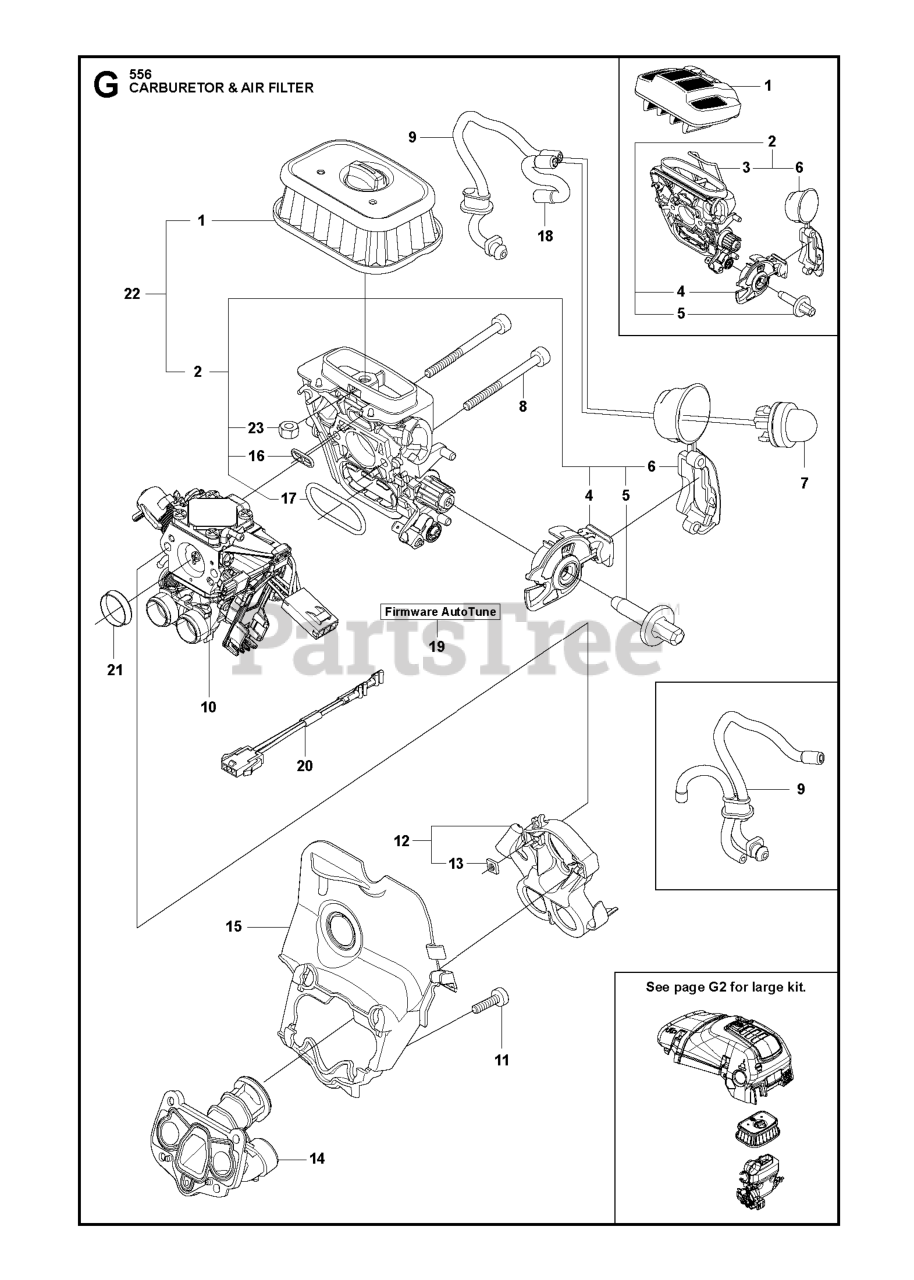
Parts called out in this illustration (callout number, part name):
3	APPLIQUE.SUBASM.GT.HUSQ.II
14	HOOD.ASM.HUSQVARNA.GT.TEX.ORAN
15	LENS.HEADLIGHT.LH.GTII.2011
18	GRILLE.SUBSTRATE.2011.
25	LENS.HEADLIGHT.RH.GTII.2011
34	PLATE.ENGINE.10GA.CRD.GENII
36	SCREW 5/16"
37	FENDER.TEX.SRD.CRD.BASE
52	LOCKNUT
62	BOLT D
68	Screw 5/16-18 x 1/2 Hex, Self Tapping 5/16-18 x 1/2
118	WASHER
130	SCREW.#10 X 0.750.BOS
137	BUMPER DASH
150	AIR DUCT.GTV2(1.66"RING HEIGHT
151	BRACKET.PIVOT.HOOD.GT.HUSQ.II
152	SHIELD.BROWNING.PNT.GT.V2
159	SCREW, 3/8-16X3/4
162	SCREW.HI-LO.CONSOLE
175	PLATE.CROSSMEMBER.HUSQ
176	SCREW.#10-24X5/8.RN.QU
177	BUSHING STEERING
178	CARGO.ASM.NET.TXGT.W/C
180	WELDMENT.CHASSIS.TEX.CRD.GEN.2
182	DASH DASH LOWER
183	BOLT.5/16-18X1-1/4 FULL THD
189	SCREW
191	INSERT.REFLECTIVE.RH.HUSQ.GTII
194	NUT LOCK HEX FLANGE 5/16-18
195	PLUG.HOLE.DASH.LOWER.12V.BLK
198	INDICATOR.DECK.LIFT.RED
199	PLATE DECK LIFT
202	VENT.SIDE.RH.GT.HUSQ.II.
203	VENT.SIDE.LH.GT.HUSQ.II.498
204	VENT.TOP.EXTERNAL.FILL.GT2.GRE
205	SIDE.TRIM.RH.GT.HUSQ.II
206	SIDE.TRIM.LH.GT.HUSQ.II.GRAY
207	BEZEL LIGHT.RH.GT.II.MYLAR
208	BEZEL LIGHT.LH.GT.II.MYLAR
213	BOLT
214	CLIP.RETAINER.TINNER.
217	ROD.PIVOT.HOOD
218	X-PIECE.HOOD.STOP.NON/
228	STUD.FASTNER.W/ANTI-ROTATE
229	LID.EXT.FILL.GT.HUSQ2.BLACK
234	BUMPER.HOOD.TEX.HUSQVARNA
235	SPACER FENDER
236	NUT.CENTERLOCK.5/16-
282	CLIP.RETAINER.CONSOLE.LT.HUSQ
283	CONSOLE.DECKLIFT.CRDII.498
287	SCREW 1/4X20
297	INSERT.REFLECTIVE.LH.HUSQ.GTII
308	BOLT.5/16-18UNCX3/4 W/SEMS.BLK
309	BACKPLATE.ASM.TEX.CRD.GEN2.1
319	LEVER.BAG.CRDII.ANTIROTATION
334	BRACKET.ENGINE
335	COVER.LOWER.DASH.RH.BLACK
336	COVER-LH.LOWER.DASH.GT2.BLACK
338	BOLT BOLT SHOULDER
339	LEVER LEVER BAGGER
340	BATTERY.DOOR.TEX.CRD.GEN.2,1
342	SUPPORT SUPPORT FENDER
343	CLIP CLIP
344	CONTROL.EZ.MULCH.TEX/CRD
345	RP KNOB.OVAL.TAPERED.3/8-16BLK
347	HITCH HITCH TOW TEX CRD GEN 2
349	BRACKET.SUPPORT.LRVB/CRD
350	CLIP.X-MAS.TREE
366	BRACKET.RH.FRONT.BAGGER.BLACK
367	BRACKET.LH.FRONT.BAGGER.BLACK
368	FULL.LEVER.BAGGER.TEX.CRD
